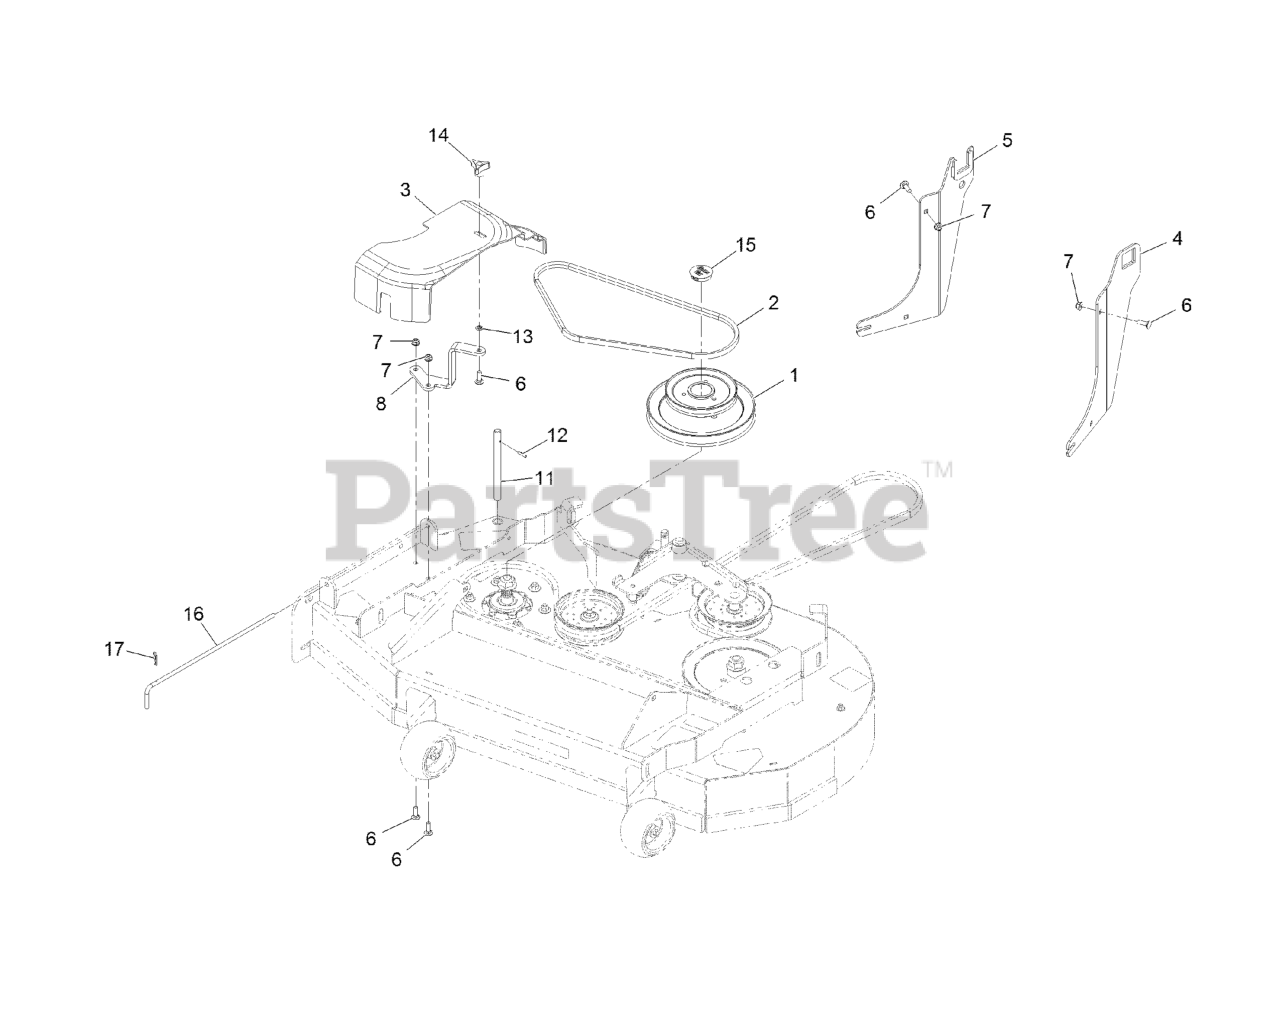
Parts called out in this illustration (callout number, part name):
1	JACKSHAFT,44 UV
2	BELT, BLOWER DRIVE 72
3	COVER-BELT, UV 44
4	BRACKET ASM, LH
5	BRACKET ASM, RH
6	BOLT-CARR
7	NUT-HF, NI
8	BRACKET-BELT COVER 44
11	SHAFT-CATCHER, GRASS
12	PIN-ROLL
13	RING-RETAINING, BOLT
14	KNOB-3 PRONG
15	PLUG, BLACK NYLON 1.75
16	PIN,CHUTE PIVOT
17	PIN-COTTER
